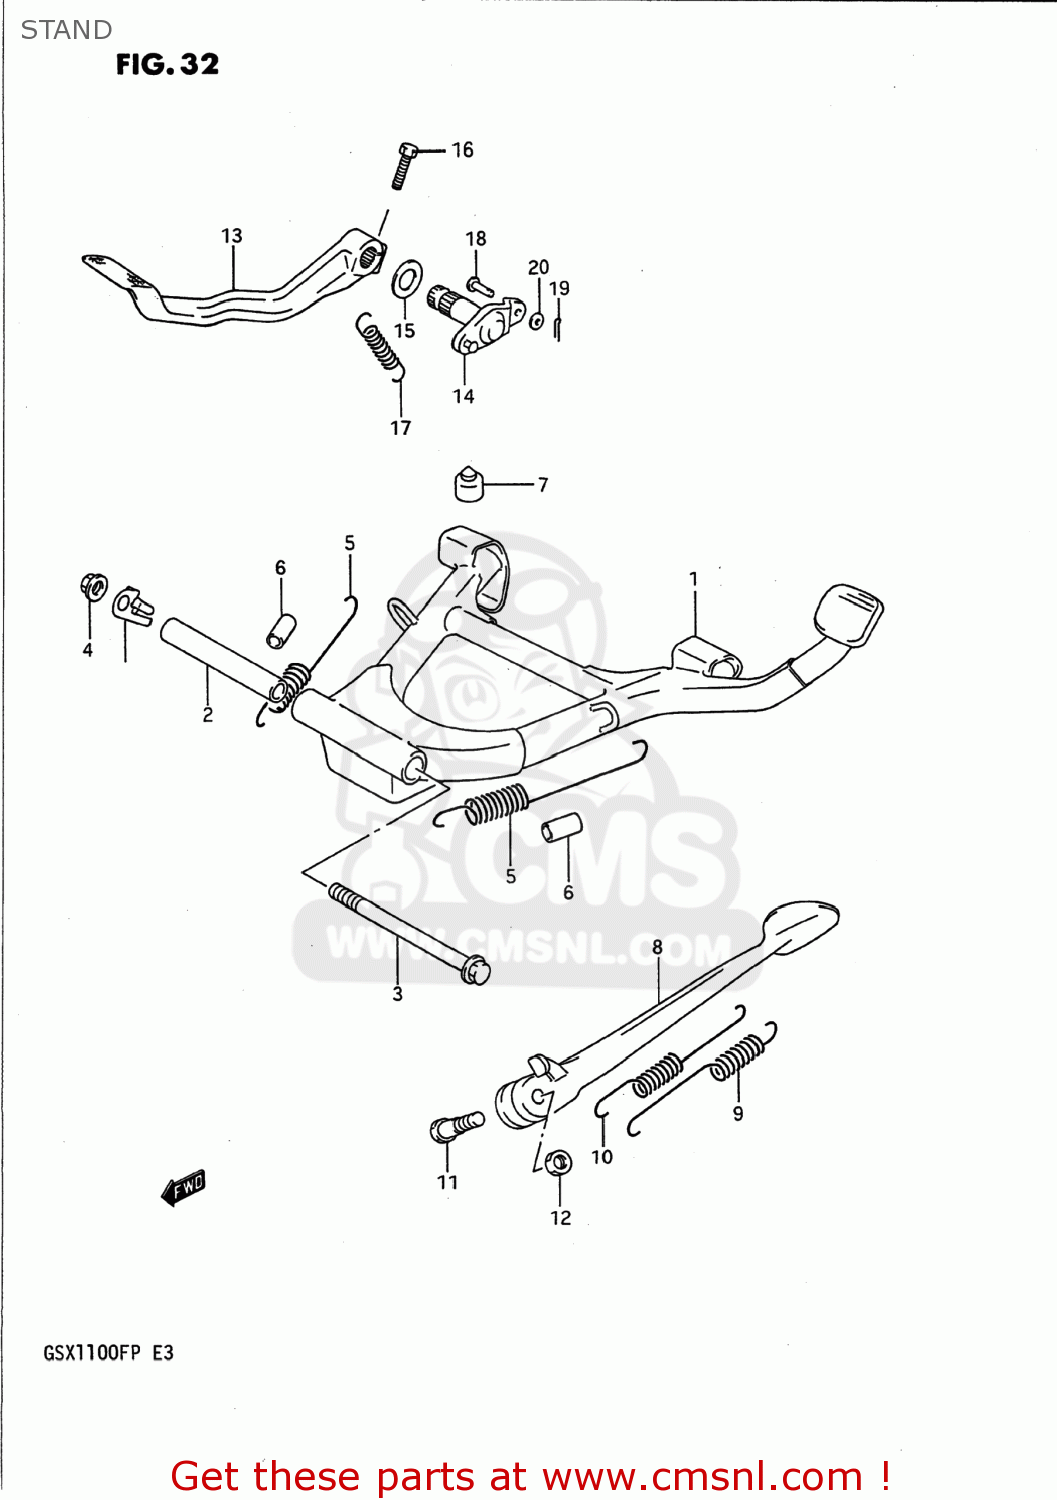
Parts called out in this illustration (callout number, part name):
1	STAND,CENTER
2	SPACER (10.5X16X102)
3	BOLT(10X132)
4	NUT
5	SPRING
6	HOSE
7	CUSHION
8	STAND,SIDE
9	SPRING
10	SPRING
11	BOLT(10X38)
12	NUT
13	PEDAL,BRAKE
14	ARM,BRAKE PEDAL
15	WASHER,BRAKE BOSS
16	BOLT
17	SPRING
18	PIN
19	PIN
20	WASHER
